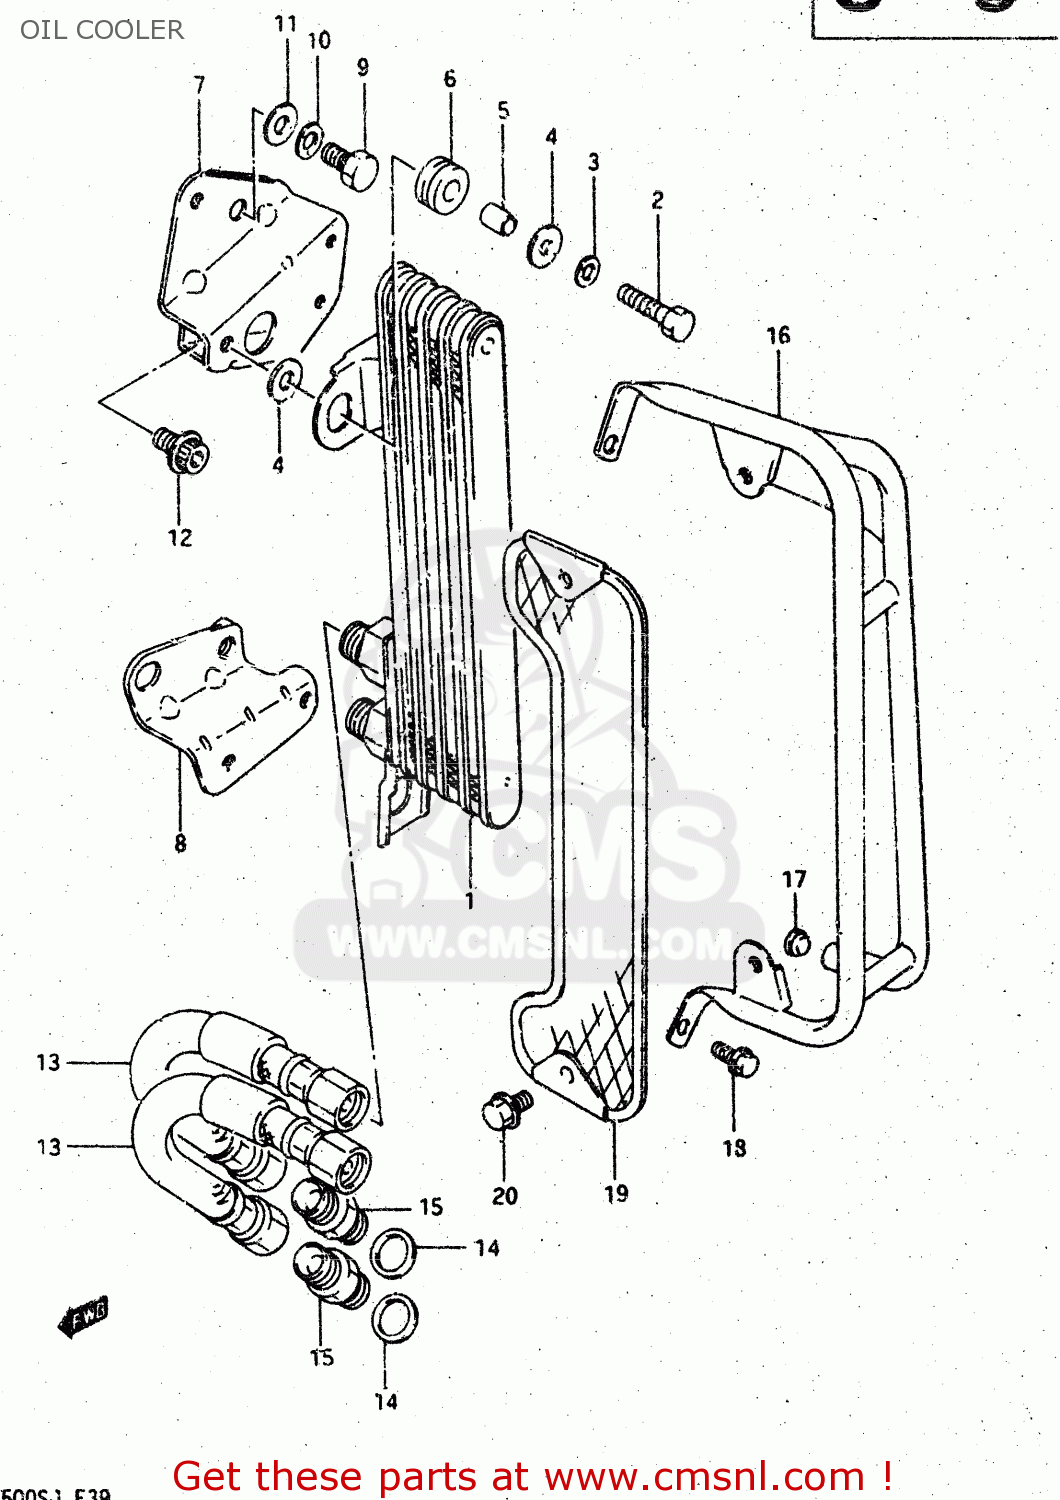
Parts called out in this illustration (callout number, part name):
1	COOLER ASSEMBLY,ENGINE OIL
2	BOLT
3	WASHER,LOCK
4	WASHER (6.5X18X1.6)
5	SPACER (6.8X10X10)
6	CUSHION
7	BRACKET,OIL COOLER NO.1
8	BRACKET,OIL COOLER NO.2
9	BOLT
10	WASHER,LOCK,8.
11	WASHER
12	BOLT
13	HOSE,OIL COOLER
14	GASKET(14X20X1.5) (NAS)
15	BOLT UNION
16	GUARD,OIL COOLER
17	CAP(OD:10)
18	BOLT
19	BUMPER,OIL COOLER
20	BOLT 6X12
